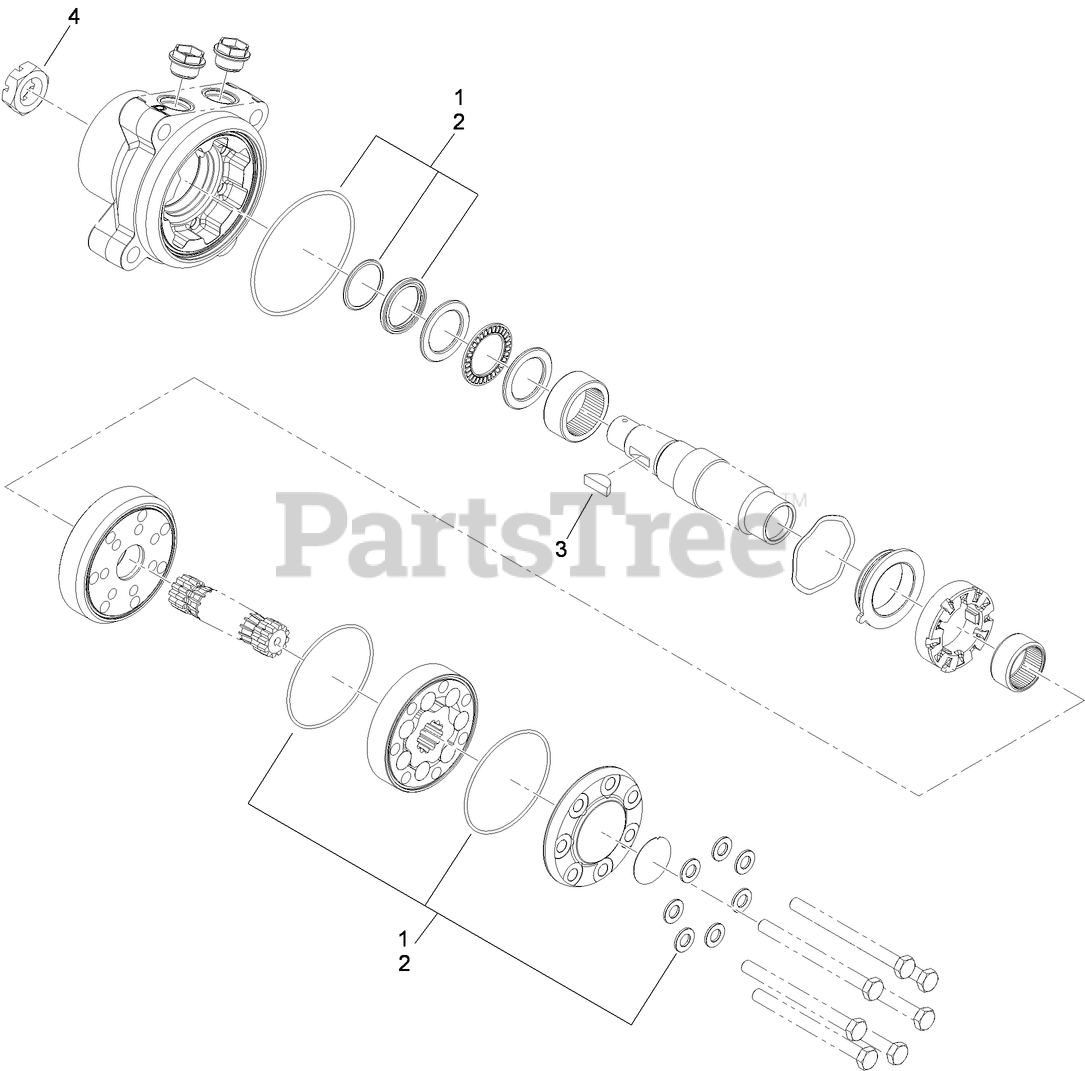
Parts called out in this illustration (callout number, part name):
1	WHEEL MOTOR SEAL KIT
2	WHEEL MOTOR SEAL KIT
3	KEY-WOODRUFF
4	NUT-HH
